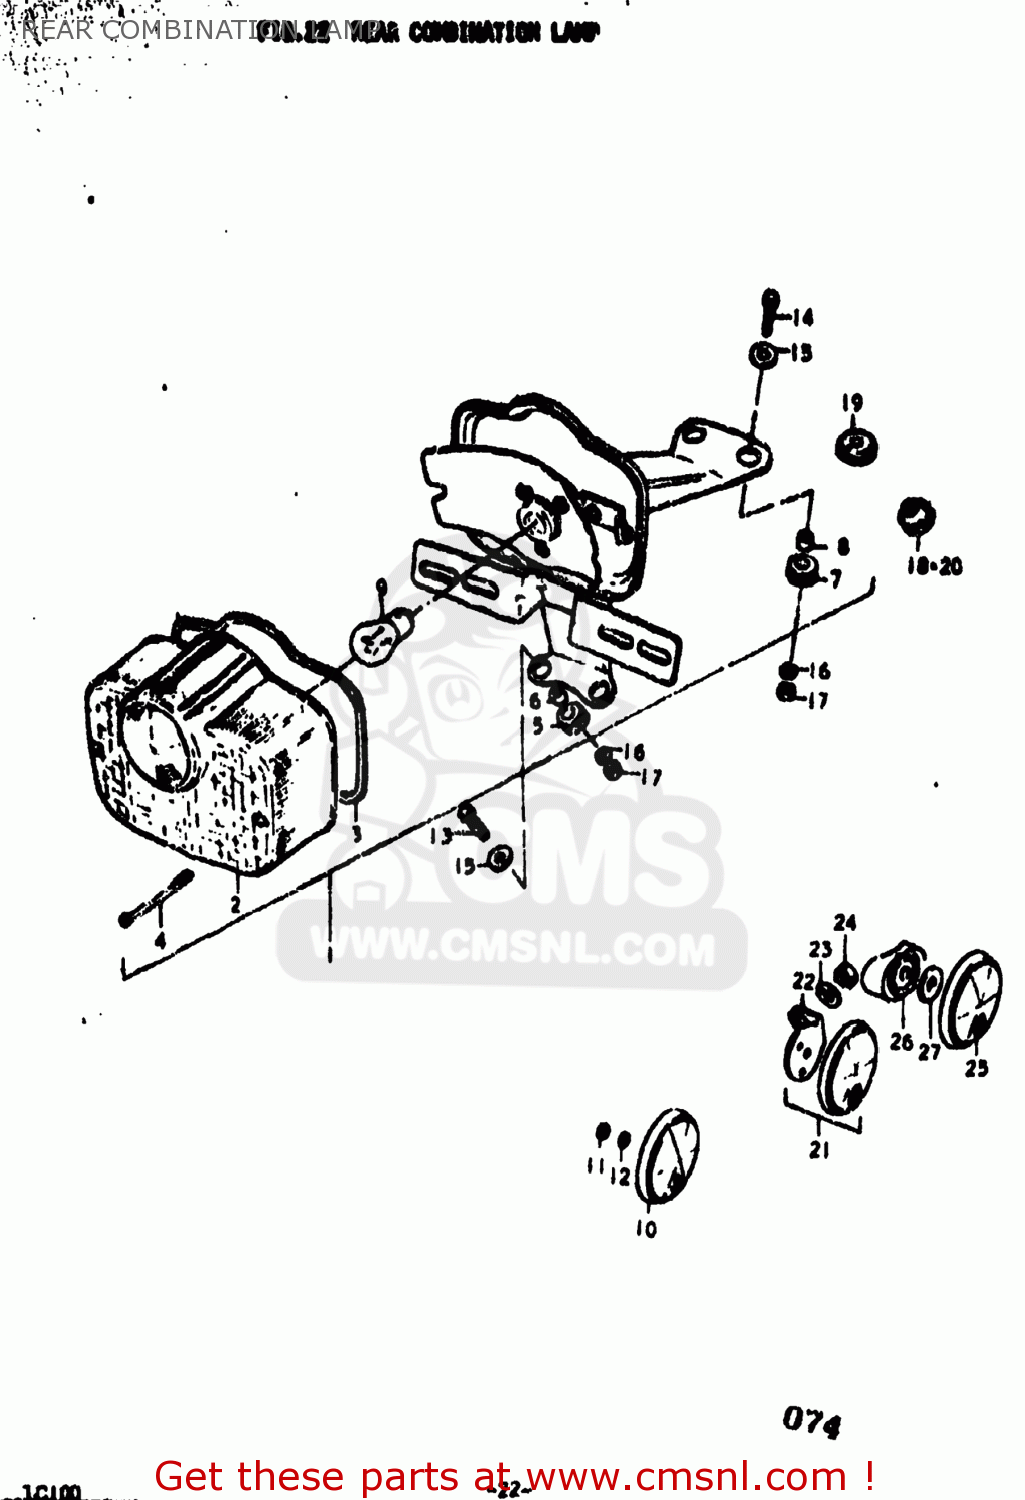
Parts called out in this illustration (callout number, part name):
1	LAMP ASSEMBLY,REAR COMBINATION
2	LENS,REAR COMBINATION LAMP
3	GASKET (NAS)
4	SCREW
5	CUSHION
6	SPACER,REAR COMBINATION LAMP
7	CUSHION
8	SPACER,REAR COMBINATION LAMP
9	BULB(6V32/3CP,STANLEY)
10	REFLECTOR,REFLEX
11	NUT
12	LOCK WASHER
13	BOLT
14	BOLT
15	WASHER
16	LOCK WASHER
17	NUT
18	GROMMET
19	GROMMET
20	GROMMET
21	REFLEX REFLECTOR ASSEMBLY
22	SPACER
23	LOCK WASHER
24	NUT
25	REFLEX REFLECTOR ASSEMBLY
26	SPACER
27	WASHER (6.5X20X1.2)
